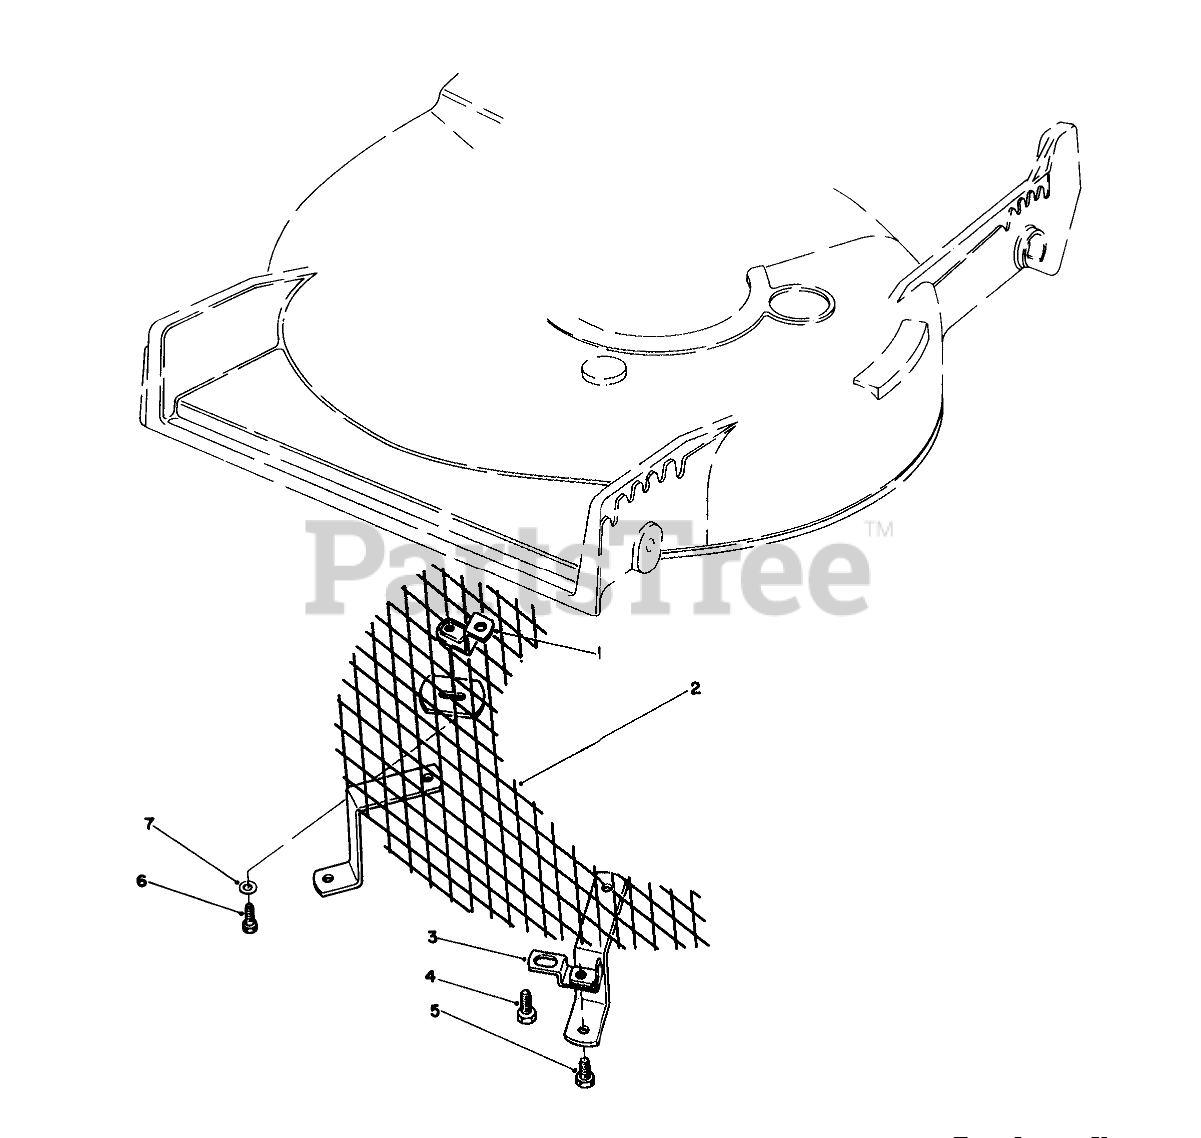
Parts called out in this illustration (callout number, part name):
1	BRACKET WA
2	SCREEN WA
3	MTG. BRACKET W.A.
4	SCREW-HWHTF
5	SCREW-HH
6	SCREW-HH
7	WASHER-FLAT
